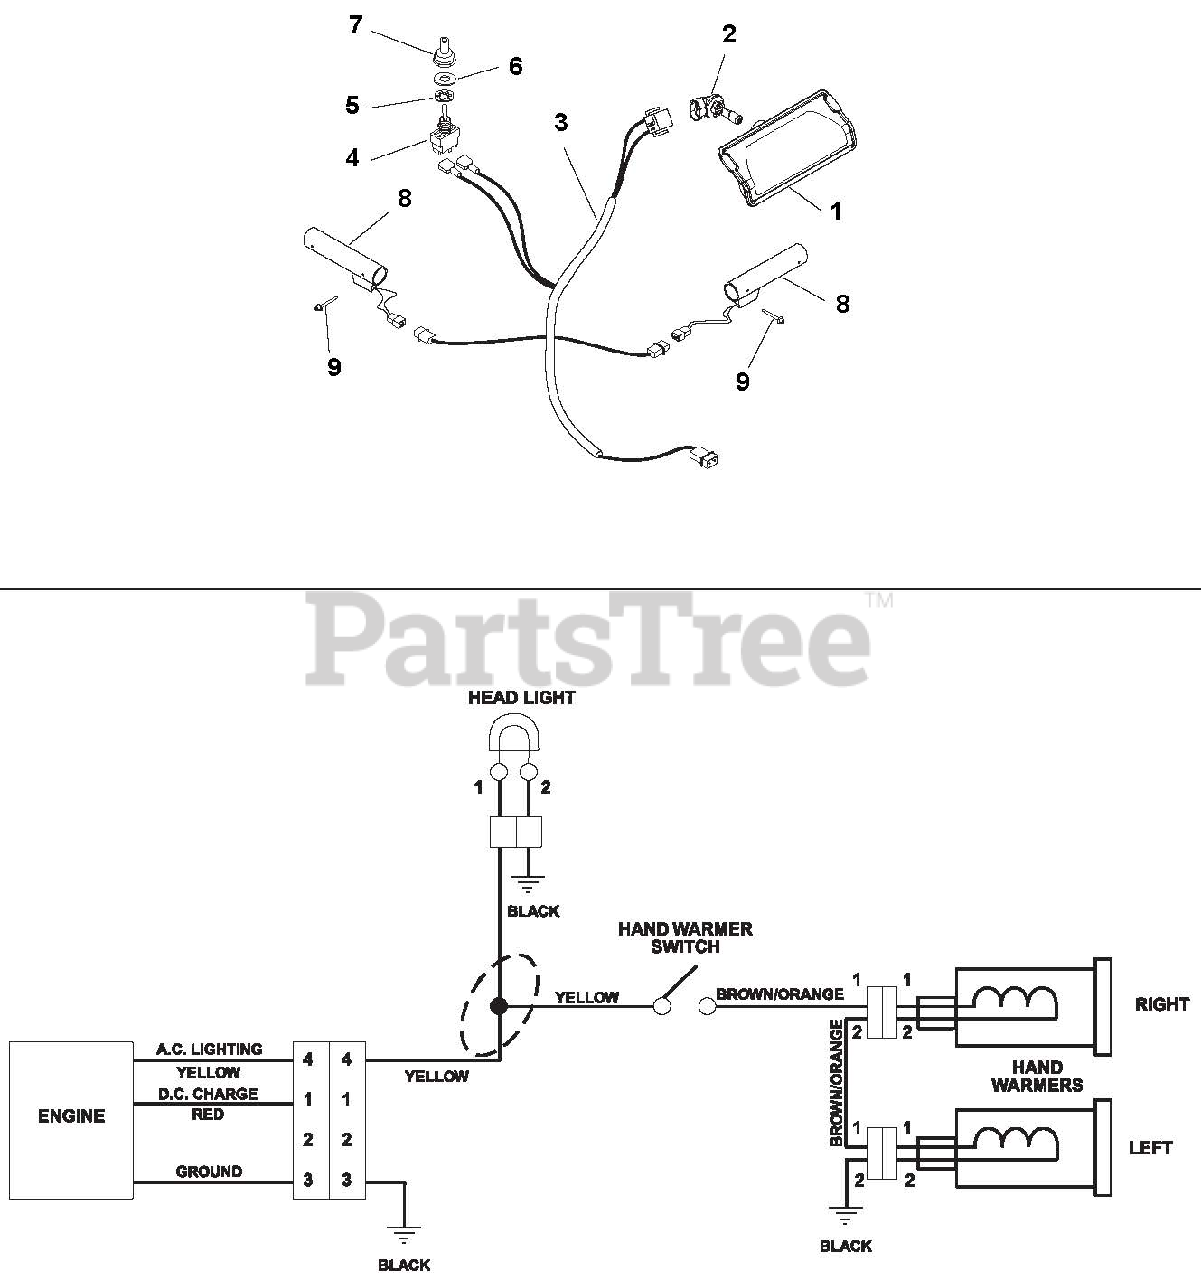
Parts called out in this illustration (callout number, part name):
1	HEADLIGHT ASY, HALO 20W 2SHOT
2	BULB, LIGHT-HALOGEN 20W
3	HARNESS, LIGHT & WARMER
4	SWITCH, ON/OFF
5	WSHR-LK-INT .563X.040 YWZC
6	WSHR-FL-STL .505X.875X.024 PL
7	BOOT, SWITCH
8	HEATED GRIP, MAGURA
9	RVT-POP #43 .125X.313 STL ZINC
